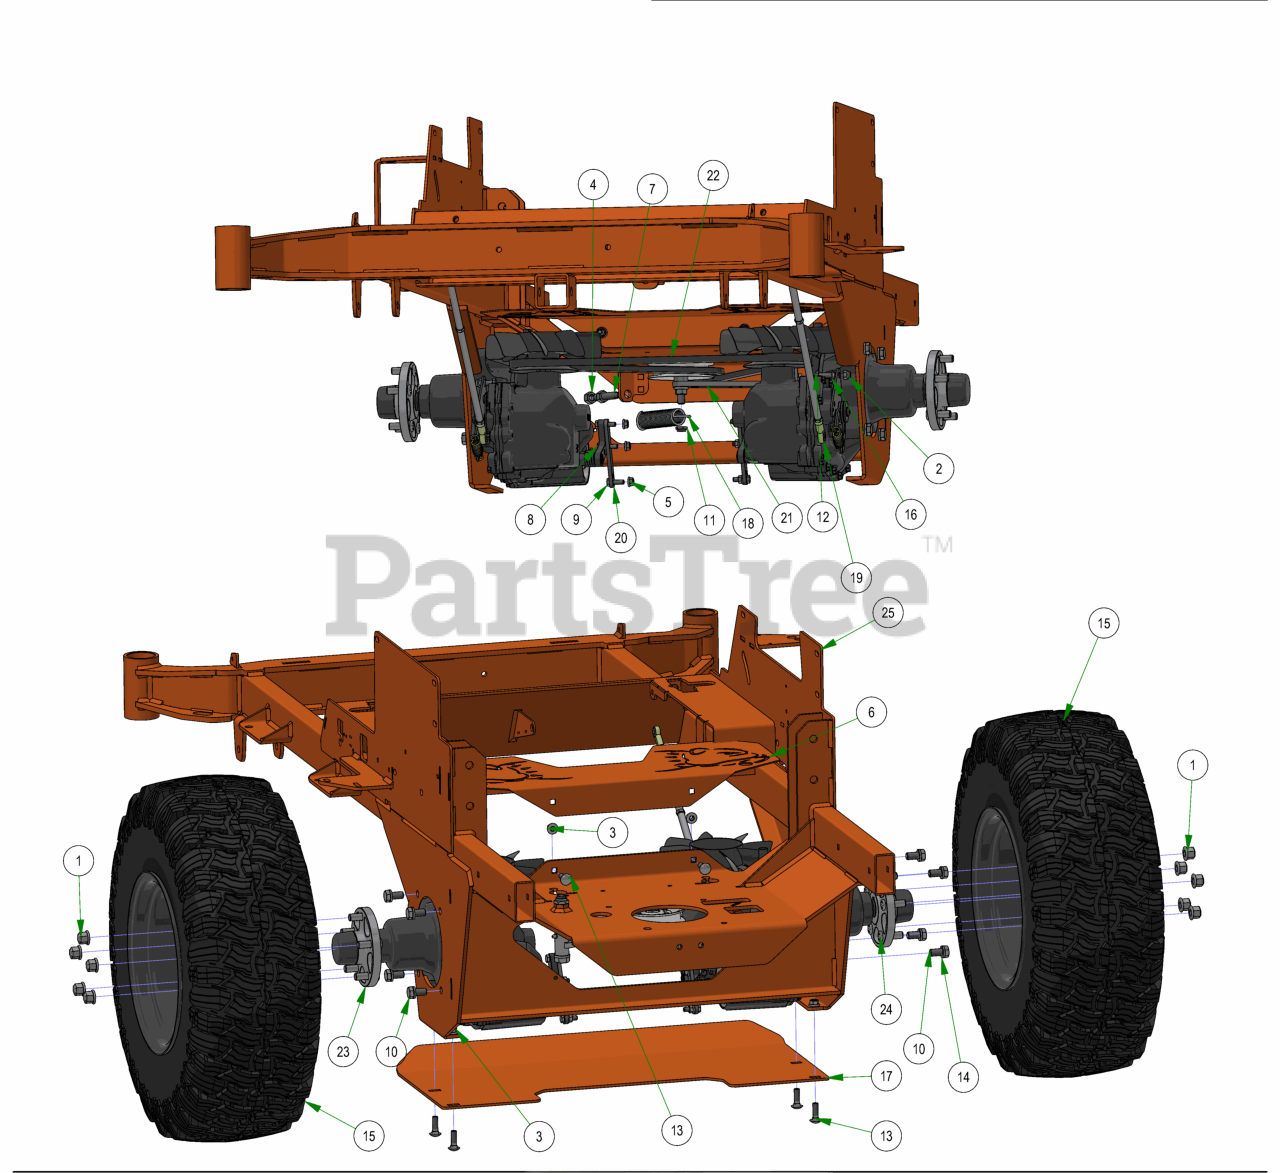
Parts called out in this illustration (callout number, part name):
1	Acorn Lug Nut
2	3/8-16 NYLON INSERT LOCKNUT ZINC
3	3/8-16 NYLON INSERT FLANGE LOCKNUT (GR.F) ZINC
4	1/2-13 HEX NUT ZINC
5	5/16-18 NYLON INSERT FLANGE LOCKNUT ZINC
6	2019 Rigid Fan Guard
7	All Thread
8	5/16-18 X 1-1/4 HEX C/S (GR.5) ZC
9	5/16-18 X 1 HEX CAP SCREW (GR.5) ZINC
10	1/2-13 X 1 HEX CAP SCREW (GR.5) ZINC
11	1/2-13 NYLON INSERT JAM LOCKNUT ZINC
12	3/8-16 X 1-1/4 HEX CAP SCREW (GR.5) ZINC
13	3/8-16 X 1-1/4 CARRIAGE BOLT ZINC
14	1/2 SPLIT LOCKWASHER (GR.8) ZINC/YELLOW
15	24x12-12 Reaper Turf Tire & Wheel Assembly
16	Drive Arm Transaxle Spacer
17	2019 Outlaw Rigid Skid Plate
18	Deck spring big diameter
19	2024 Rebel Push Rod Assembly
20	2015 Outlaw Brake Adapter (4400 Transaxles Only)
21	2019 Rebel Pump Idler
22	2019 Rebel Pump Belt
23	4400 Transaxle-Left-Base Outlaw/2019 Rebel
24	4400 Transaxle-Right-Base Outlaw/2019 Rebel
25	2023 Rebel Frame - Painted
